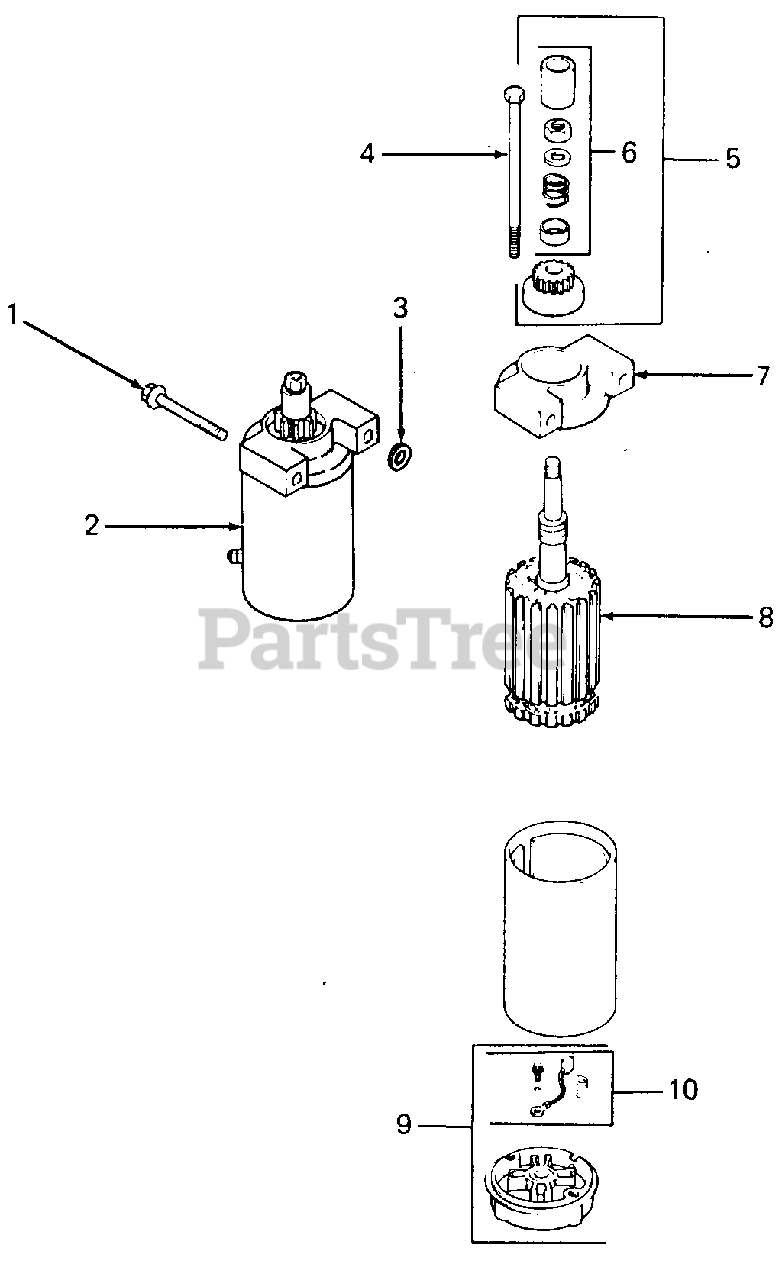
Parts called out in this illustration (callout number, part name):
1	Screw, Bendix Starter, M8 X 1.25 X 65.5
2	Starter, Bendix Assy
3	Washer, Flat
4	Screw, Hex Flange, 1/4-20 X 4-1/4
5	Kit, Drive
6	Kit, Drive Parts
7	Cap, Drive End
9	Cap, Commutator End Assy
10	Kit, Brush
